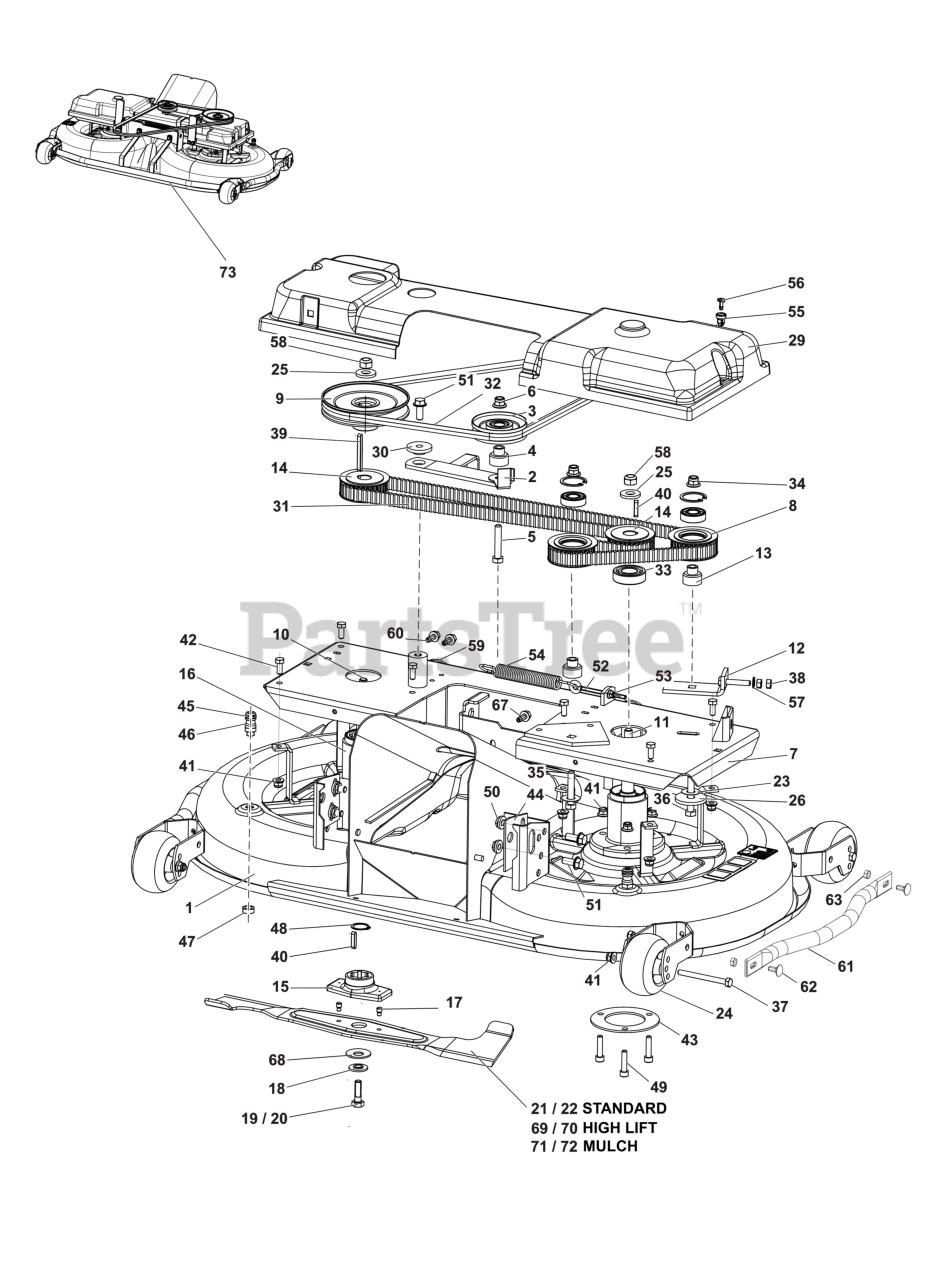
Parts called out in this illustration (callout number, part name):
1	MOWER DECK
7	CASE, Main
12	FOOT, Mounting
17	STUD ( 100 PCS )
21	BLADE, Left, 102cm
22	BLADE, Right, 102cm
29	COVER, Pulley
43	PLATE, Reinforcement
45	CONNECTOR
61	BUMPER, Tube
69	BLADE, High Lift, Left, 102cm
70	BLADE, High Lift, Right, 102cm
71	BLADE, Mulch, Left, 102cm
72	BLADE, Mulch, Right, 102cm
73	KIT, Mower Deck
